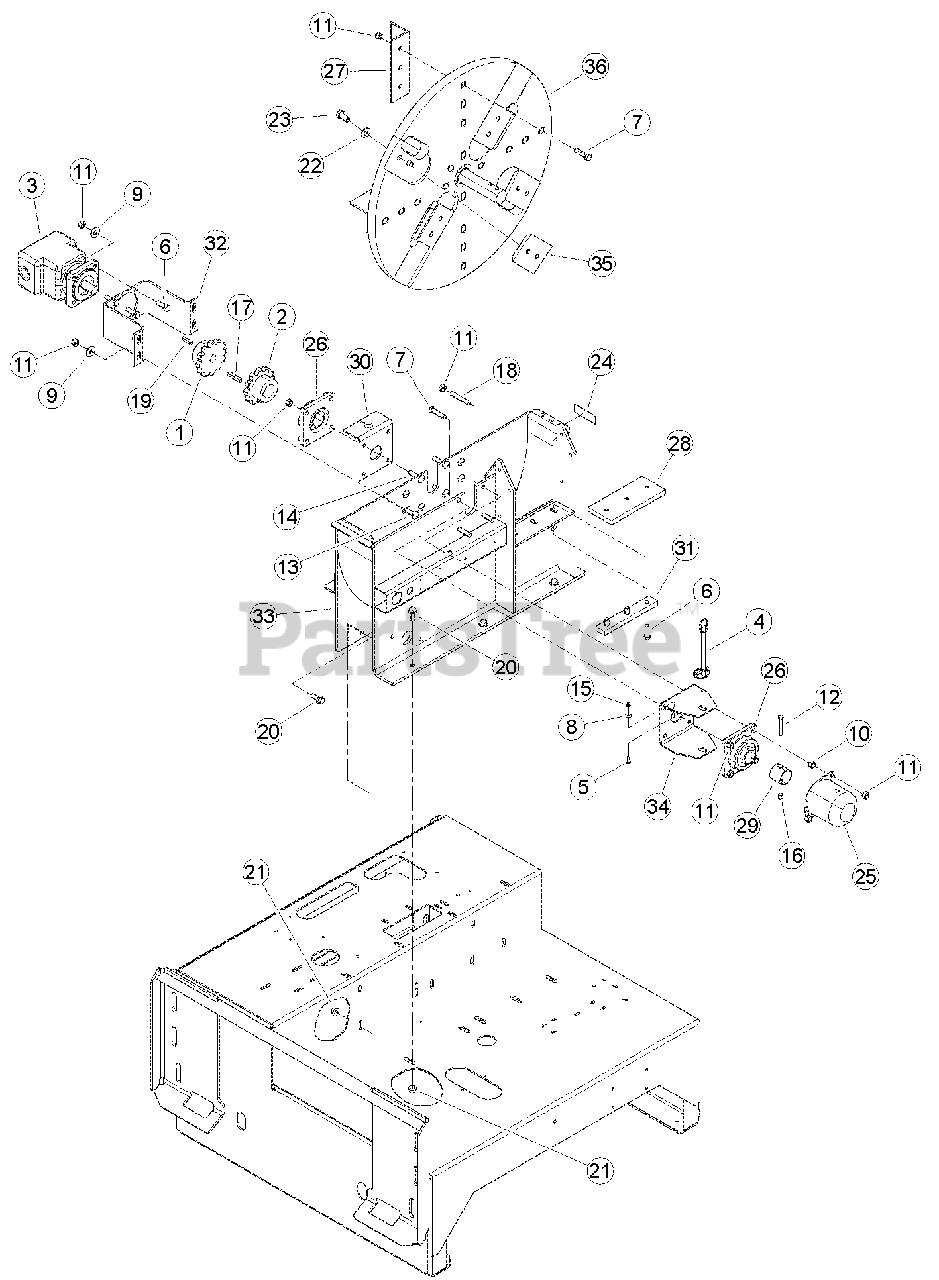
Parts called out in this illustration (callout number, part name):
1	COUPLER, CHAIN 1" ID
2	COUPLER, CHAIN 1-3/4" ID
3	MOTOR, 3.45 CU IN HYDRAULIC
4	PIN, HITCH 1/2 X 6-1/2 W LYNCH
5	BOLT, 1/4 X 3/4 HEX HD GR5 ZP
6	BOLT, 1/2 X 1-1/2 HEX HD GR5 ZP
7	BOLT, 1/2 X 2 HEX HD GR5 ZP
8	WASHER, 1/4 FLAT ZP
9	WASHER, 1/2 FLAT ZP
10	NUT, 1/2 HEX NC ZP
11	NUT, 1/2 CENTERLOCK GRB ZP
12	BOLT, 3/8 X 2-1/2 HEX HD GR5 ZP
13	BOLT, 1/2"X1-1/2" GR5 ZP CRG
14	BOLT, 1/2 X 2 CRG GR5 ZP
15	NUT, 1/4 NE NYLOCK ZP
16	NUT, 3/8 NE NYLOCK ZP
17	KEY, 3/8 SQUARE X 2 LONG PLAIN
18	STUD, 1/2-13 X 3 LONG B7 ZP
19	KEY, 5/16 SQUARE X 1-1/2 LONG
20	BOLT, 1/2 X 1-1/4 SERR FLANGE
21	NUT, 1/2 SERR FLANGE NC ZP
22	WASHER, 5/8 SAE HARDENED
23	BOLT, M16 X 2.0 X 30 HEX HD W/PATCH
24	DECAL, SERIAL NUMBER
25	CAP, LARGE SHAFT
26	BEARING, 1-3/4 4 BOLT FLANGE
27	PADDLE, BIG CHIPPER
28	PLATE, CHIPPER BOTTOM
29	COLLAR, CHIPPER LOCK
30	WELDMENT, LEFT BEARING BRACKET
31	SPACER, CHIPPER ANVIL
32	MOUNT, HYDRAULIC MOTOR
33	WELDMENT, ROTOR HOUSING
34	BRACKET, DISK LOCK
35	BLADE, BIG CHIPPER
36	ASSEMBLY 9" CHIPPER DISK
